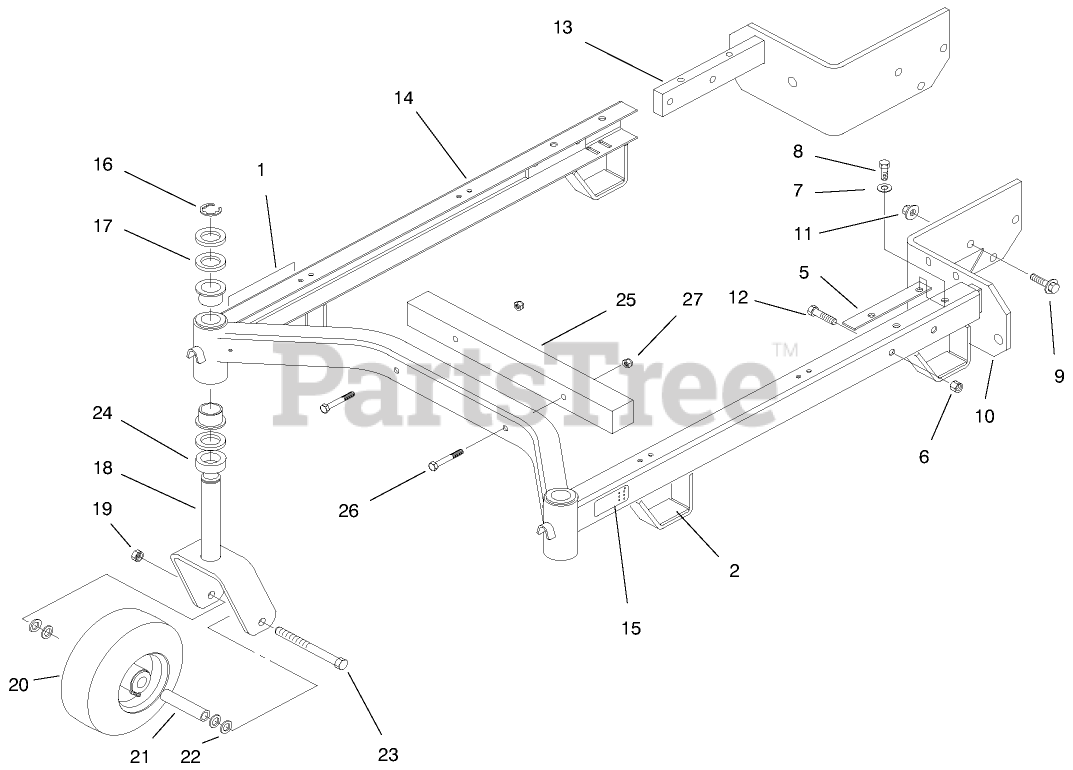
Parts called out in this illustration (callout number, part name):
1	DECAL-HOC, LH
2	CUSHION-RUBBER
5	SHIM-CARRIER
6	NUT-LOCK, CONE
7	WASHER-FLAT
8	SCREW W/PATCH
9	SCREW-HHF
10	Bracket-LH
11	NUT-HF
12	SCREW-HH
13	Bracket RH
14	WA - SUSPENSION
15	DECAL-HOC, RH
16	RING-RETAINING
17	WASHER-THRUST
18	Castor Fork
19	NUT-HEX
20	CASTOR WHEEL ASM
21	SPANNER-TIRE
22	WASHER-FLAT
23	SCREW-HH
24	SPACER-CASTOR
25	Weight
26	SCREW-HH
27	NUT-LOCK, NI
